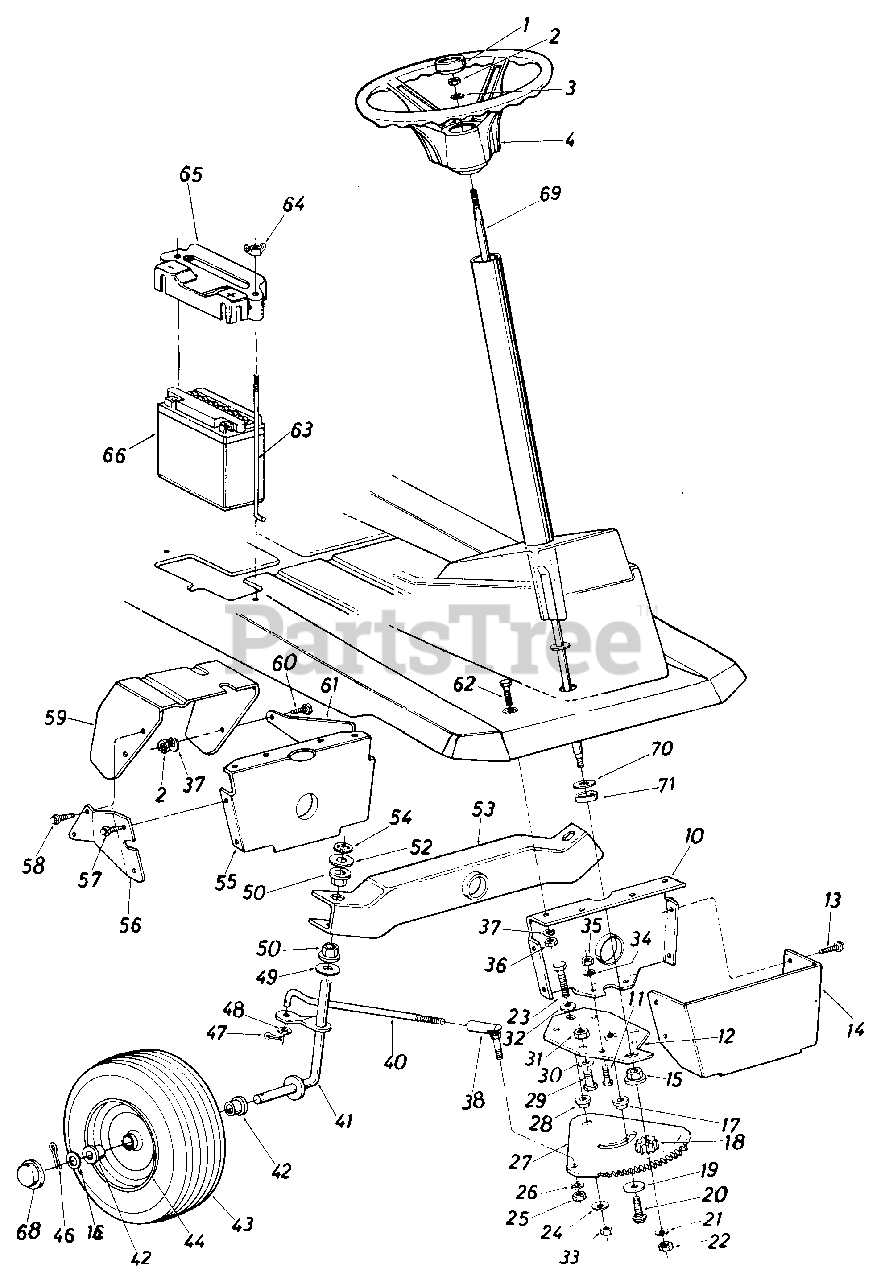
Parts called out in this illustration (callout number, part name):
1	CAP-STEER WHEEL
2	NUT-HEX CENTER L-5/16-18
3	WASHER-BELL .337 X .867 X .057
4	STEERING WHEEL ASSY
10	BRACKET-PIVOT BAR
11	SCREW-HEX 5/16-18 X .75
12	BRACKET-ST GEAR SUP
13	SCREW-HEX WASH HD
18	GEAR-PINION
20	SCREW-HEX SLF TAP 3/8 X 1 3/8
21	WASHER-FL (#46041)
22	NUT-5/16-24
23	SCREW 3/8-24 X 1.25 GR5
25	NUT-HEX 3/8-24
26	WASHER-LOCK-3/8
27	SEGMENT-STEERING
29	SCREW-NYLON
30	WASHER-FL-.531 X .930 OD X .050
31	NUT-HEX 1/2-13
32	WASHER-BELL .400 ID X .88 X .060
33	NUT-HEX 3/8-24
34	WASHER-LOCK-5/16
35	NUT-HEX 5/16-18
38	JOINT ASSY-BALL
40	ROD-STEER TIE
41	AXLE ASSY-RH
42	BEARING-FLANGE
43	WHEEL
44	WHEEL
46	PIN-COTTER-1/8 DIA X 1.25
47	PIN-COTTER-1/8 DIA X 1.00
48	WASHER-FL-.385 ID X .87 OD X .06
49	WASHER-FL-.635 ID X 1.12 OD X .090
50	BEARING-FLANGE
52	WASHER-FL-.635 ID X 1.12 OD X .090
53	BAR ASSY-PIVOT
54	NUT-PUSH-SPEED
55	BRACKET-PIVOT BAR
56	BRACKET-REINF-RH
57	SCREW-HEX WASH HD
58	TIE-PUSH MOUNT
59	PEDAL ASSY-BRAKE
60	SCREW-HEX 5/16-18 X .75
61	BRACKET-REINF-LH
62	SCREW-HEX 5/16-18 X .75
63	BATTERY HOLD DOWN
64	NUT-WING-SOLID 1/4-20
65	COVER-BATTERY
66	BATTERY
68	HUB CAP
69	SHAFT ASSY
70	WASHER-FL-.640ID X 1.24OD X .06HDN
71	SPACER
